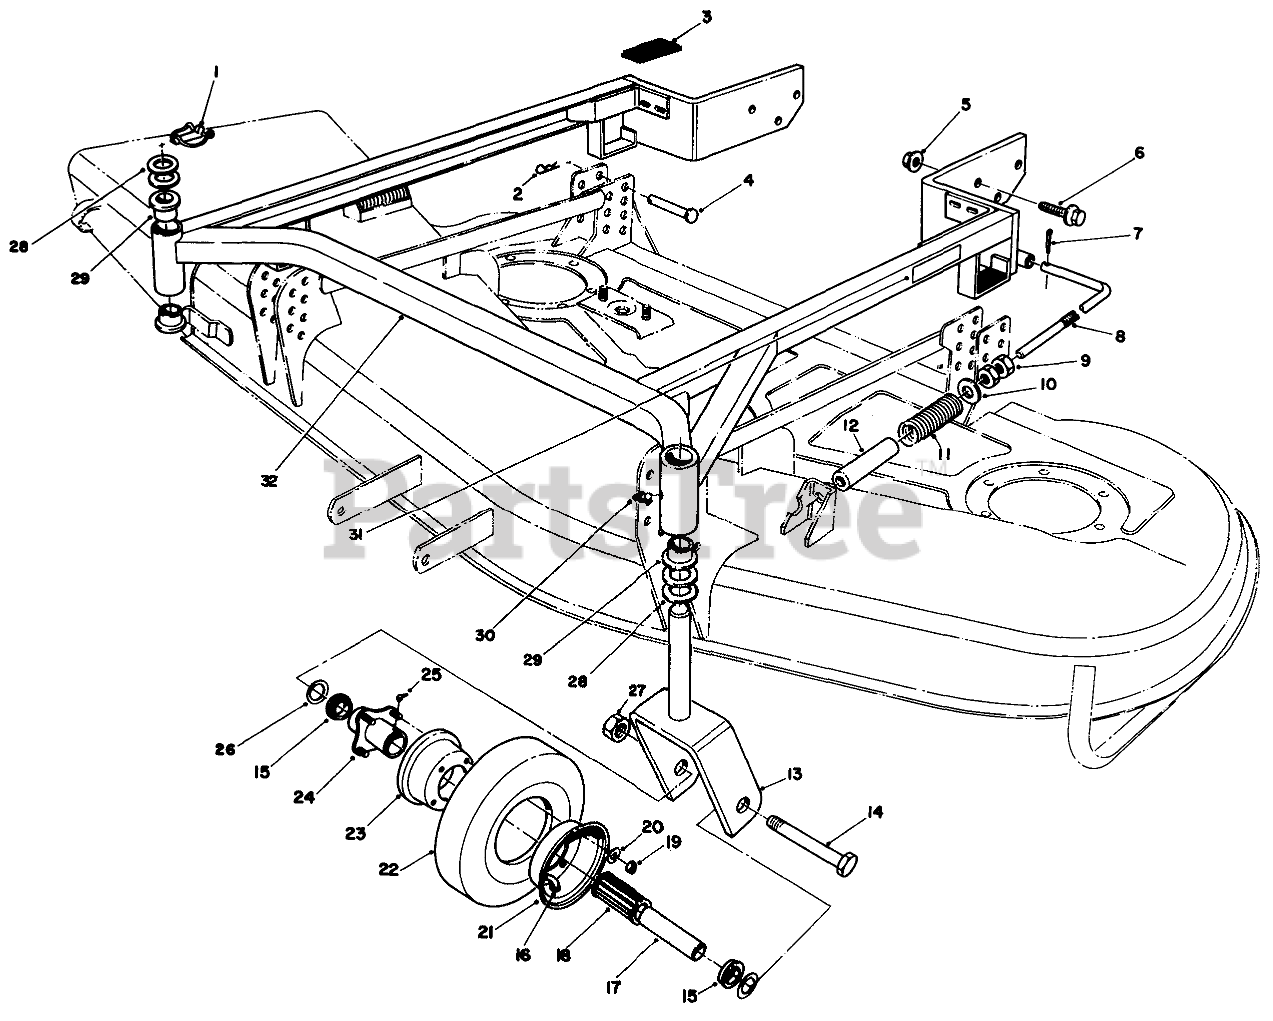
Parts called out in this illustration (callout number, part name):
1	PIN-LYNCH
2	PIN-HAIR
3	Cushion-Rubber
4	PIN-CLEVIS
5	NUT-HF
6	SCREW-HHF
7	PIN-COTTER
8	ADJUSTING SHAFT
9	NUT-JAM
10	WASHER
11	COMP. SPRING
12	SLEEVE-TUBE, 36 INCH
13	Castor Fork
14	SCREW-HH
15	BEARING-OUTSIDE
16	TUBE-INNER (W/VALVE)
17	SPANNER-TIRE
18	BEARING-ROLLER
19	NUT-HEX
20	WASHER-LOCK
21	MALE WHEEL HALF
23	FEMALE WHEEL HALF
24	HUB-CENTER
25	FITTING-GREASE
26	WASHER-FLAT
27	NUT-HEX
28	WASHER-THRUST
29	Bushing
30	FITTING-GREASE
31	Frame-Carrier (Incl. Ref. #30)
32	DECAL-HOC, LH
